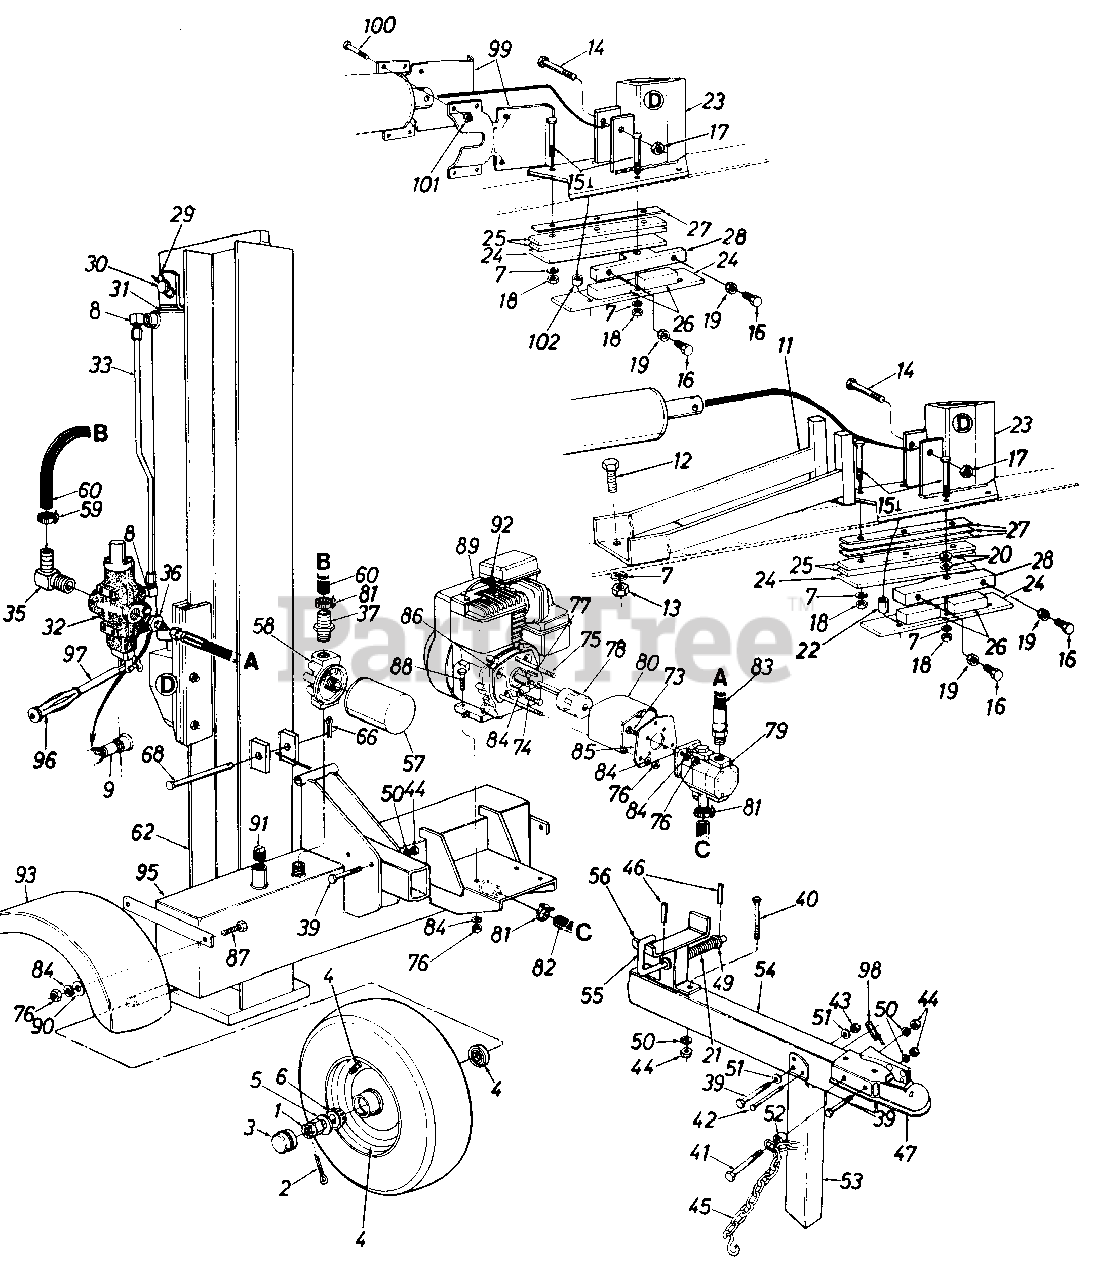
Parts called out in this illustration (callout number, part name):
1	Slotted Nut 3/4-16 Thd.
2	Cotter pin 5/32" Dia.
3	Hub Cap
5	Fl-Wash. .76" I.D. x 1.5" O.D.
6	Roller Bearing
7	L-Wash 1/2" I.D.*
8	90ø Solid Male Adaptor
9	Pipe Nipple 1/2 NPT
11	Stripper Ass'y.
12	Hex Bolt 1/2-13 x 2.0" Lg. (Grade 8)
13	Hex Nut 1/2-13 Thd. (Grade 5)
14	Hex Bolt 1/2-20 x 3" Lg. (Grade 8)
15	Hex Bolt 1/2-20 x 2.75" Lg. (Grade 8)
16	Hex Bolt 3/8-24 x 1.5" Lg.
17	Hex L-Nut 1/2-20 Thd.
18	Hex Nut 1/2-20 Thd.
19	Hex Jam Nut 3/8-24 Thd. (Grade 5)
20	Fl-Wash. .53" I.D. x .94"
21	Comp. Spring 4" Lg.
22	Spacer 1/2" I.D. x .86" Lg.
29	External Cotter Pin
30	Cylinder Mounting Pin
31	Hydraulic Cylinder
33	Metal Pressure Tube
35	Return Elbow
36	Adapter
37	3/4" Hose Barb.
39	Hex Bolt 3/8-16 x 3" Lg. (Grade 8)
40	Hex Bolt 3/8-16 x 4n Lg.
41	Hex Bolt 3/8-16 x 3.25" Lg. (Grade 8)
42	Clevis Pin 5/16 x 2.5" Lg.
43	Hex L-Nut 3/8-16 Thd.
44	Hex Nut 3/8-16 Thd.
45	Chain-Tow Hitch
46	Roll Pin
47	Hitch Coupler
49	Fl-Wash. .635" I.D. x .93" O.D.
50	L-Wash. 3/8" I.D.
51	Fl-Wash. .406" I.D. x .75" O.D.
52	Spacer.27" Lg.
55	Locking Rod
57	Filter Element
58	Filter Head
59	Adj. Hose Clamp
60	Return Hose 3/4" I.D. x 44" Lg.
62	Vertical Beam Ass'y.
66	Cotter Pin 1/8" Dia.
68	Hinge Pin 1/2 x 4.8" Lg.
73	Hex Bolt 5/16-24 x 1 " Lg.
74	Hex Bolt 5/16-24 x .62" Lg.
75	Hex Bolt 5/16-24 x 5" Lg.
76	Hex Nut 5/16-24 Thd.
77	Sq.-Key 3/16" x .75"
78	Flexible Coupling
79	Two Volume Pump
80	Coupling Shield
81	Hose Clamp 5/8"
82	Suction Hose 3/4 I.D. x 22" Lg.
83	High Pressure Hydraulic Hose 62"
84	L-Wash. 5/16" I.D.
87	Hex Bolt 5/16-24 x .75n Lg.
88	Hex Bolt 5/16-24 x l.75n Lg.
89	Engine
90	Fl-Wash. .344 I.D. x .875" O.D.
91	L-Vent Pipe Plug
92	Spark Plug Boot
93	Fender
95	Tank Ass'y.
96	Grip
97	Control Handle
98	Spring Pin
101	Hex L-Nut 3/8-16 Thd.
102	Spacer 1/2n I.D. x .68" Lg.
